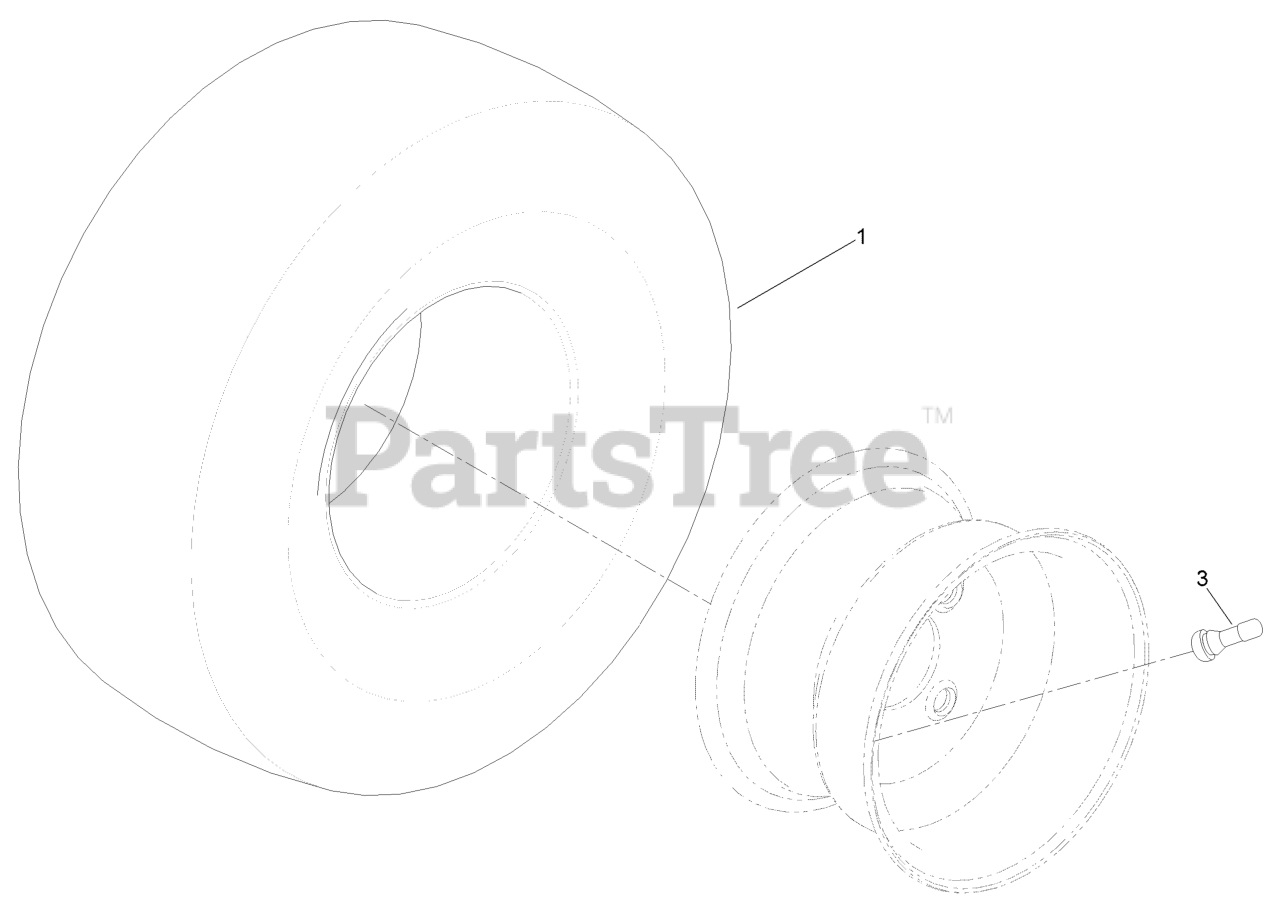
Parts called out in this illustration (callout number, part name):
1	TIRE-2 PLY
3	Stem-Valve
99	TUBE-TIRE
